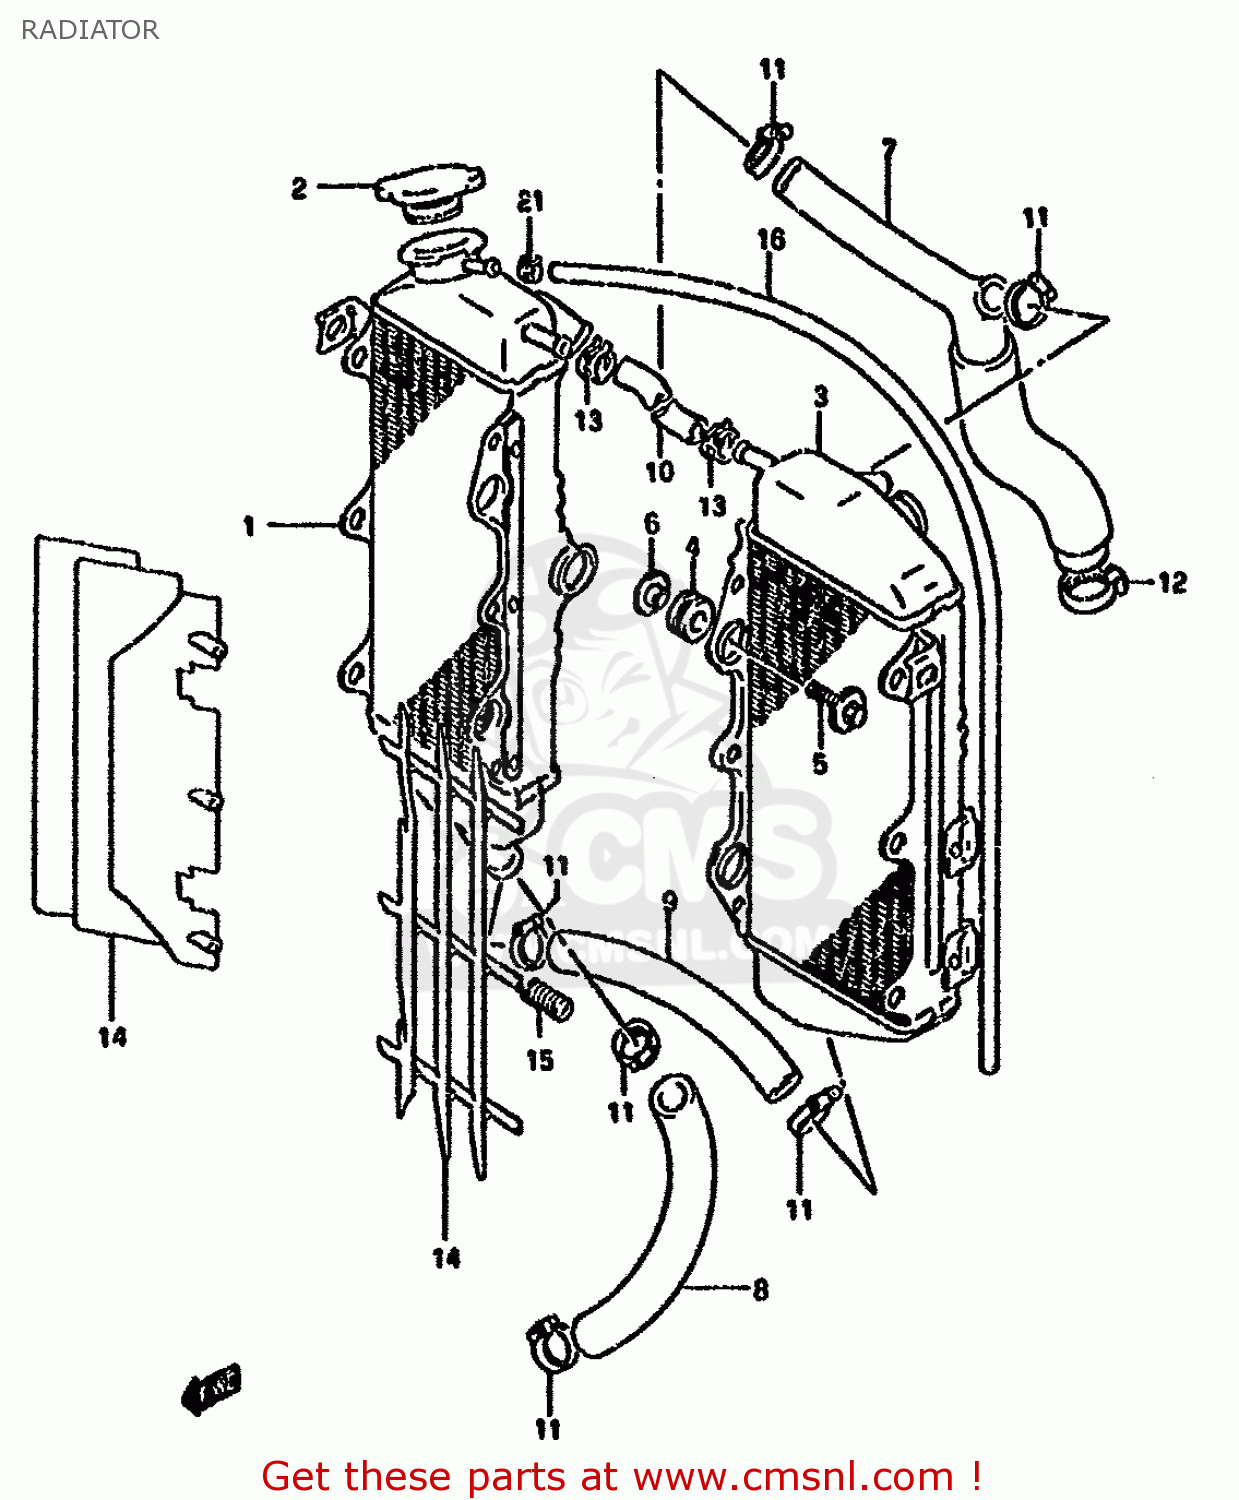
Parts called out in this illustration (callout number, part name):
1	RADIATOR,WATER RH
2	CAP,RADIATOR
3	RADIATOR,WATER LH
4	CUSHION,RADIATOR LWR
5	BOLT(6X25)
6	SPACER(6.5X10.5X14.1)
7	HOSE,RADIATOR INLET
8	HOSE,RADIATOR OUTLET
9	HOSE,RADIATOR JOINT
10	HOSE,WATER
11	CLAMP
12	CLAMP
13	CLIP
14	LOUVER,RADIATOR
15	SPRING
16	HOSE(5X8X2000)
